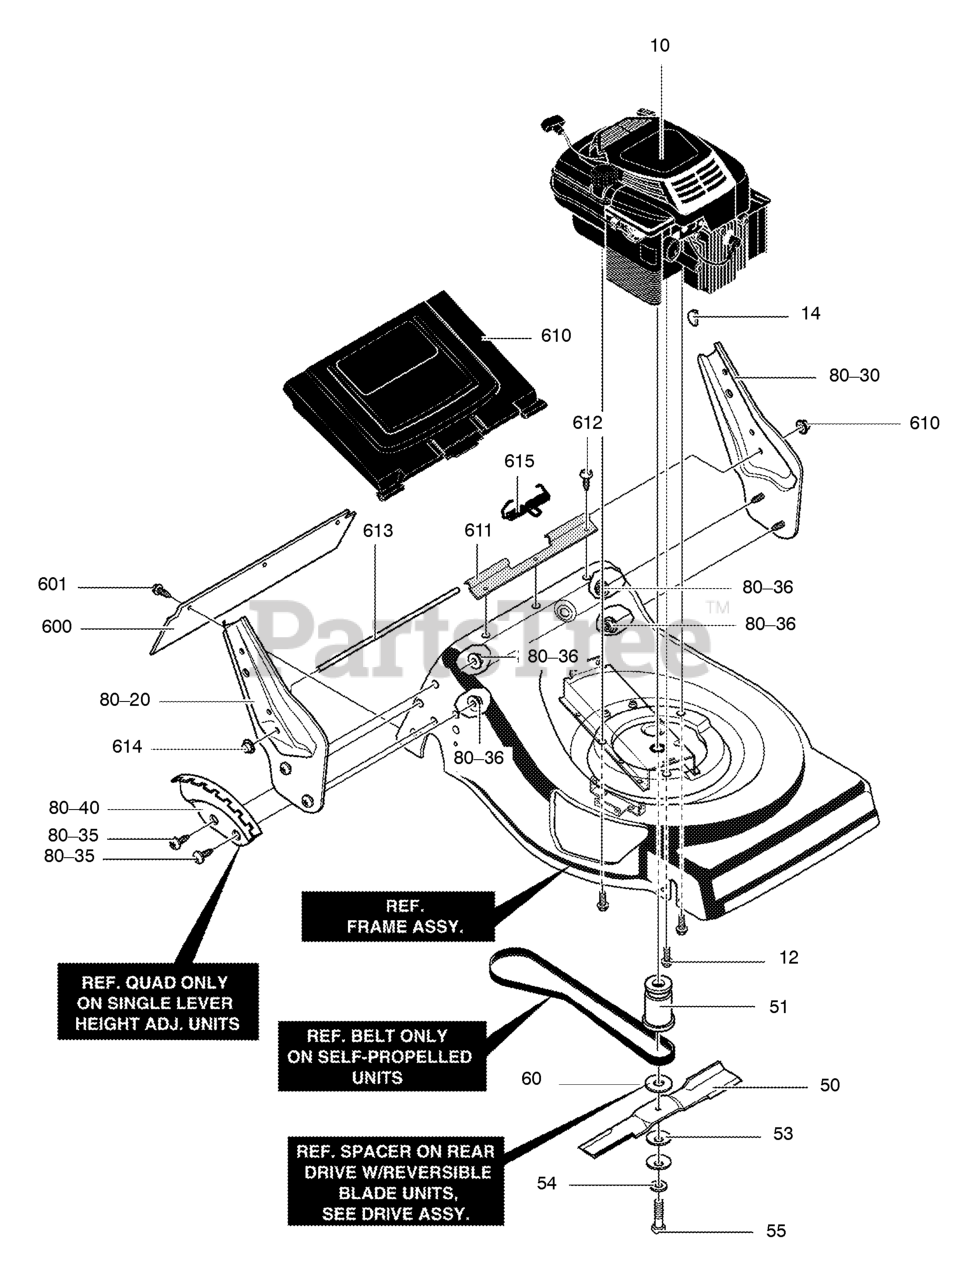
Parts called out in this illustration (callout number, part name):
10	ENGINE *
14	WOODRUFF KEY 505
50	BLADE, 21" REVERSIBLE
51	ADAPTER, BLADE 21"
53	WASHER, BEVELLE
55	SCREW, 3/8-24 x 2.00
80-20	BRACKET, HANDLE RH
80-30	BRACKET, HANDLE LH
80-35	SCREW, 5/16-18 x 0.63
80-36	NUT, 5/16-16
80-40	INDEX, HEIGHT ADJ
600	DEFLECTOR, REAR
601	SCREW, 10-16X.50
610	DOOR, REAR 21
612	SCREW, 10-16X.50
613	ROD, PIVOT
614	CAP, PUSH ON
615	SPRING, TORSION
